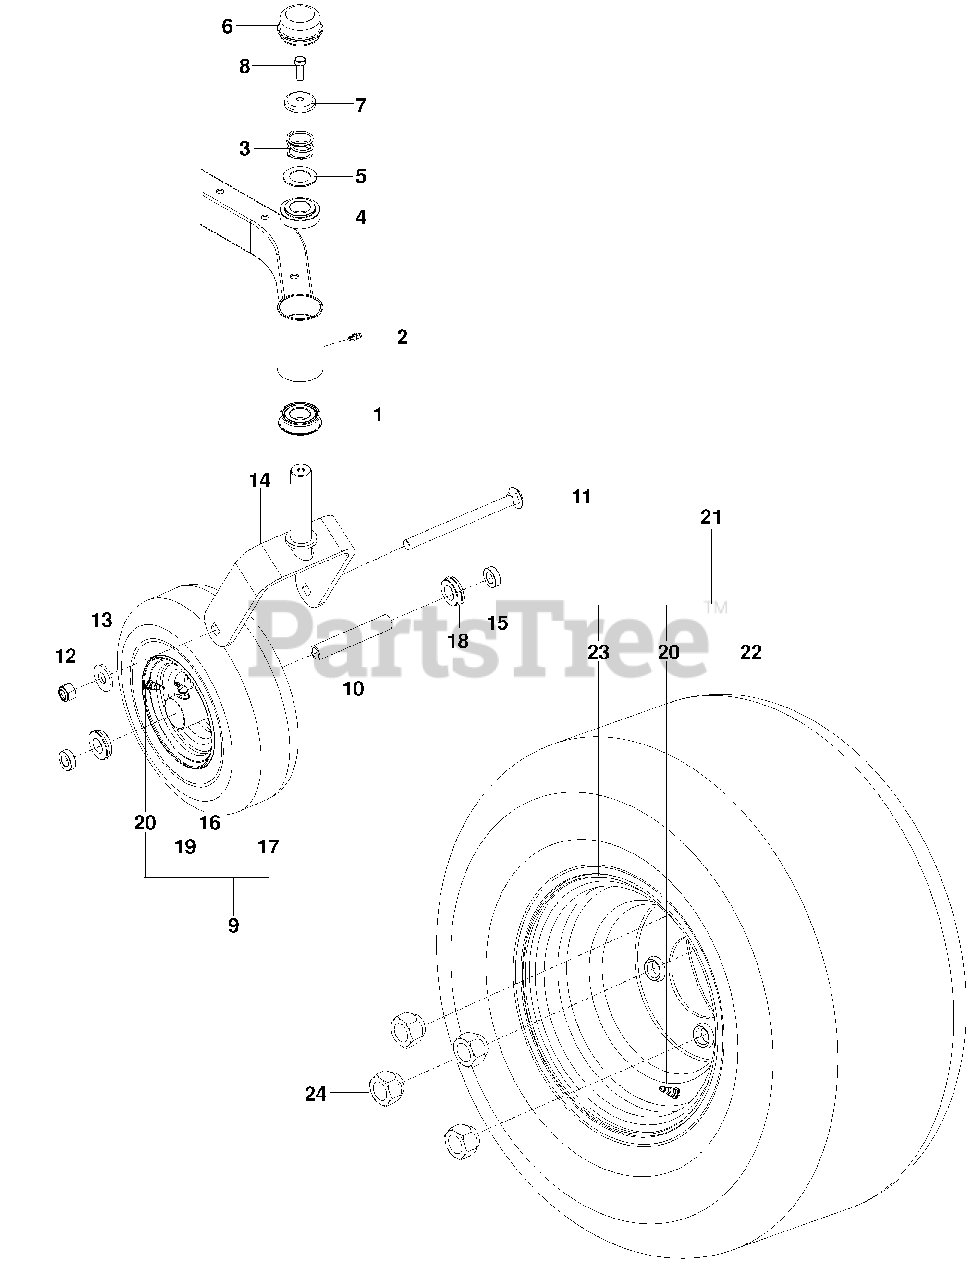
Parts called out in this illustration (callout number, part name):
1	Bearing, Flanged
2	Zerk 3/16 Drive
3	Spring, Caster
4	Bushing, Caster
6	Grease Cap
7	Plug, Caster
8	Hhb 5/16-18 X 1, W/Ny
9	Caster Tire Assy
11	Rhsnb 1/2-13 X 6 1/2
12	Nut 1/2 Hex Nyloc
13	Washer 1/2 Flat
14	Yoke Org
15	Spacer 5/16
17	Caster Tire, 410-5 4 Ply
18	Bearing, Flanged
19	Zerk
20	Valve Stem
21	Tire, Rear Assy 20 X 8-8
22	Tire Only, Rear 20 X 8-8
23	Rim 8 X 7 W/ .8" Offset
24	Nut, Lug 1/2
